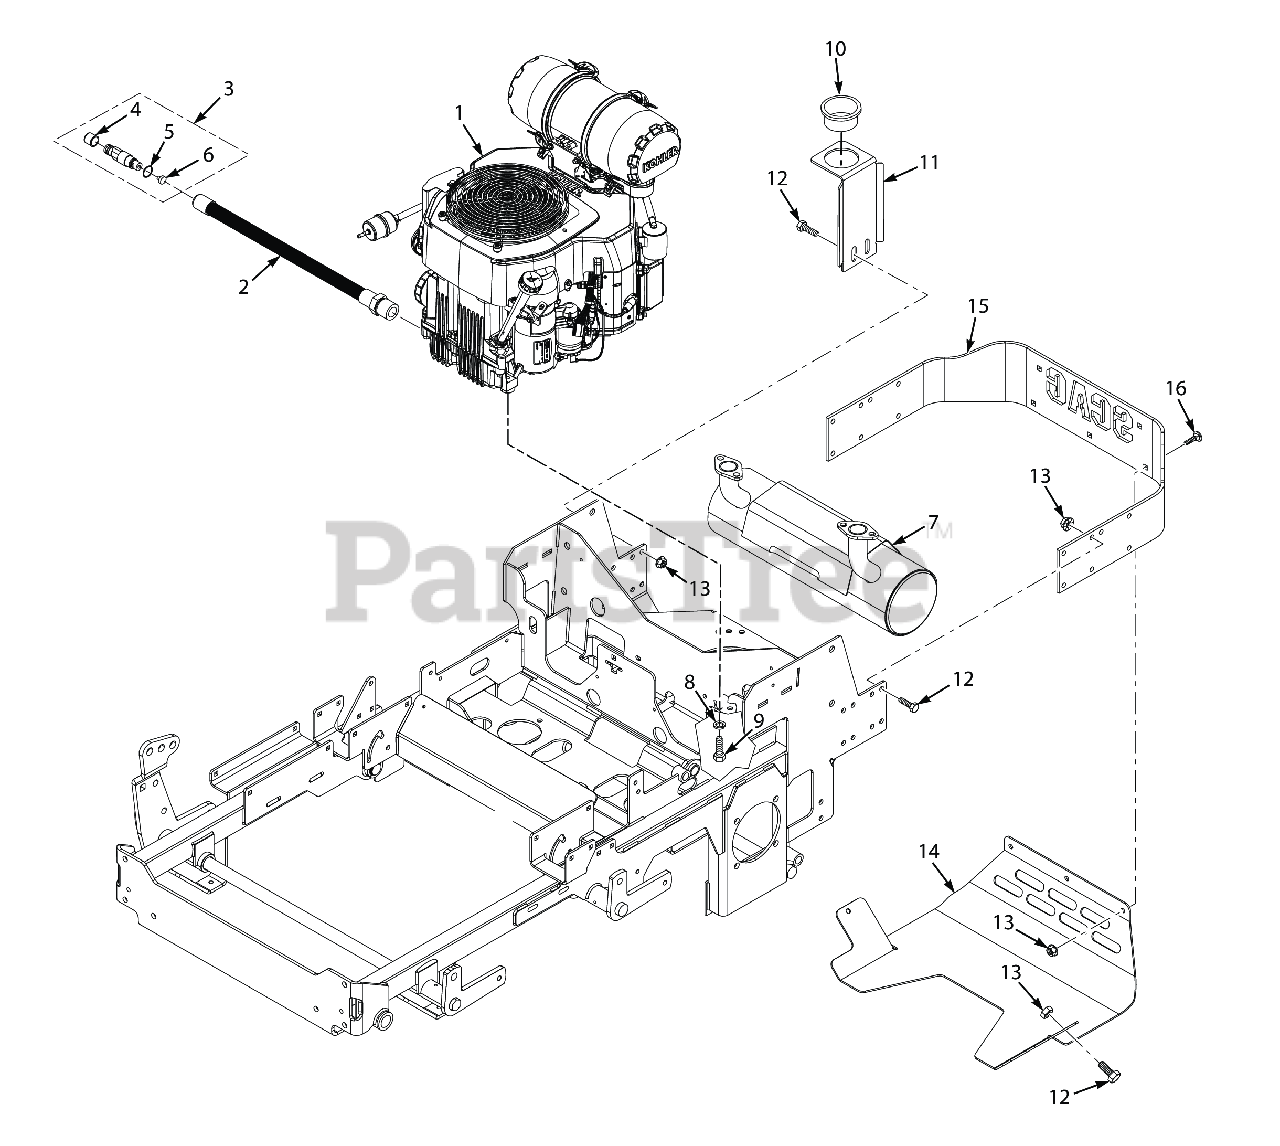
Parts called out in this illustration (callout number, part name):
1	Engine, 22 HP Kawasaki FX
1	Engine, Kawasaki 26FT-EFI
1	Engine, Kohler 23CV
1	Engine, Kohler 25CV-EFI
1	Engine, Kohler 29CV-EFI
2	Hose Assembly, Engine Oil Drain - Kawasaki FS/FX
2	Hose, Oil Drain - Kohler CV & CV-EFI
3	Adaptor, Oil Drain Hose, 29CV-EFI
4	Valve Assembly, Oil Drain
5	O-Ring
6	O-Ring
7	Muffler, Kawasaki FS/FX
7	Muffler, Kohler
7	Muffler, Kohler 25CV-EFI & 26CV-EFI
7	Muffler, Kohler 29CV-EFI
8	Lockwasher, 3/8" Spring, Kawasaki FX / FS
9	Bolt, Hex Head 3/8-16 x 1-1/4", Kawasaki FX / FS
9	Bolt, Hex Head Self-Tap 3/8-16 x 1-1/4" (Kohler x3 - 25EFI, Kohler x4 - 29EFI)
10	Bushing, Thick Panel Snap
11	Bracket, Oil Drain Hose
12	Bolt, Hex Head, 3/8-16 x 1 Gr. 5
13	NUT, 3/8-16 SERRATED FLANGE HEX HEAD
14	Plate, Skid
15	Bumper, Rear
16	Carriage Bolt, 3/8-16 x 1.0"
